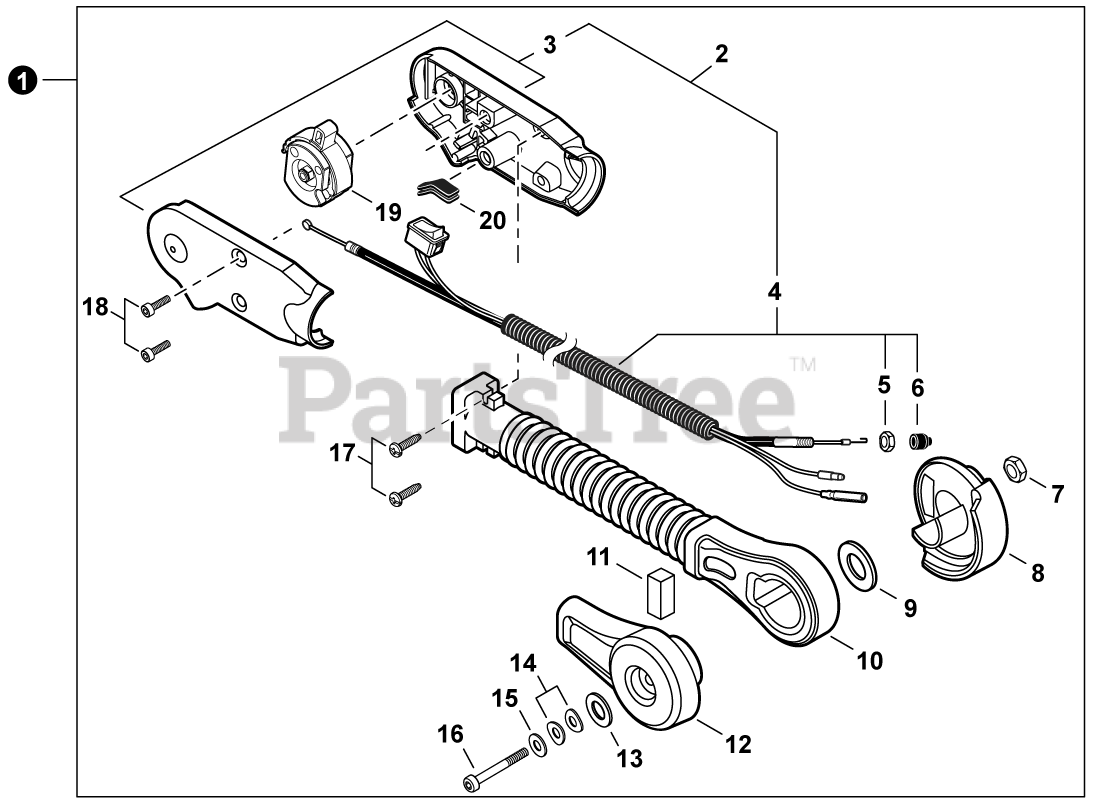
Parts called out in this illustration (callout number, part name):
1	THROTTLE CONTROL KIT - HIP MOUNT
2	THROTTLE CONTROL KIT
3	GRIP SET, THROTTLE
4	CABLE ASSY, CONTROL
5	NUT, HEX M6
6	CAP, DUST
7	NUT, LOCK M6
8	BRACKET, ARM - INNER
9	WASHER 45
10	ARM, THROTTLE CONTROL
11	SEAL, DUST - FOAM
12	BRACKET, ARM - OUTER
13	WASHER 6.5x15.5x0.6
14	WASHER, FRICTION 6.6x14.3
15	WASHER 6.6x20x1.6
16	BOLT, TORX 6x75
18	BOLT, TORX 5x16
19	CONTROL, THROTTLE
20	GROMMET
